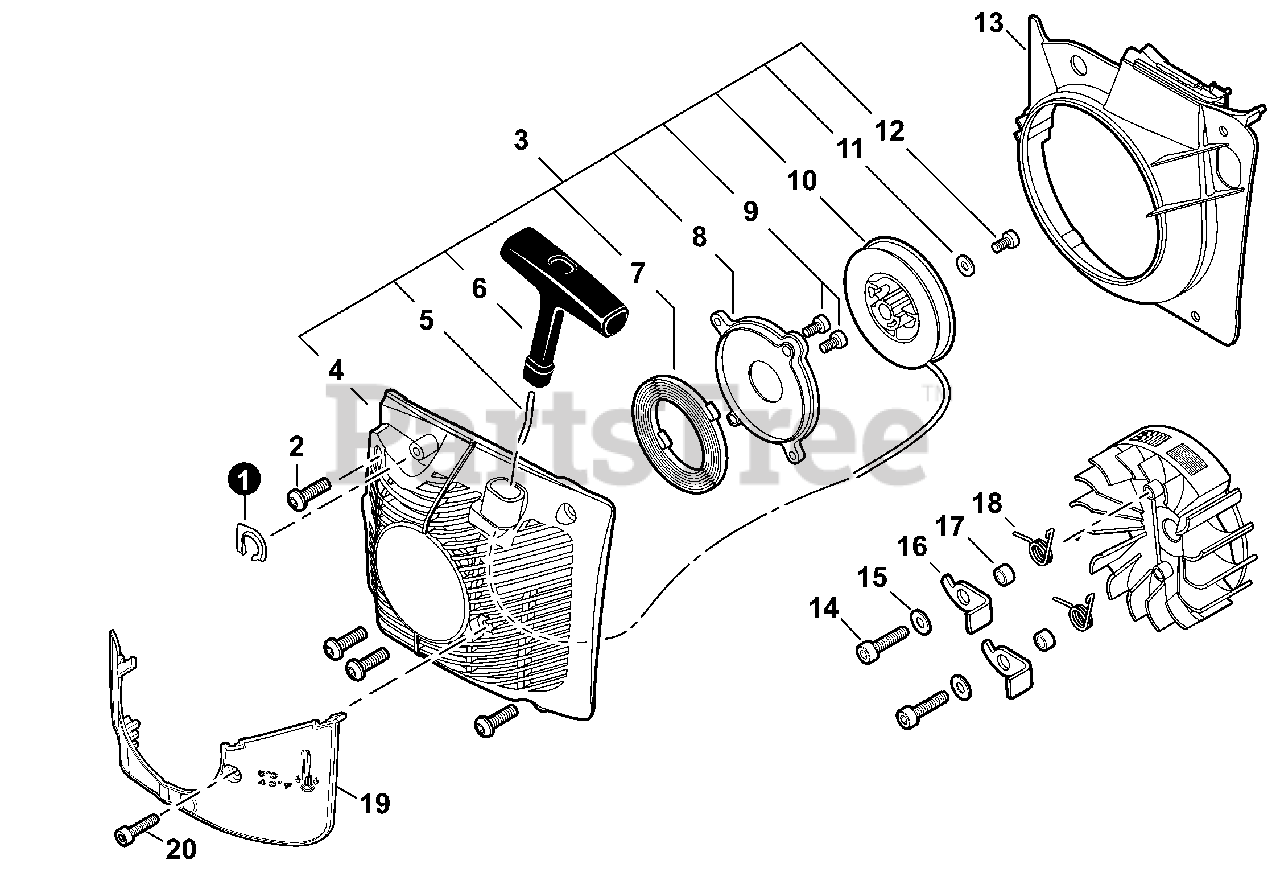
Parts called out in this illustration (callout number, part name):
1	PLATE, EYE
2	BOLT, TORX 5×20
3	STARTER ASSY, RECOIL
4	CASE, STARTER
5	ROPE, STARTER Ø4×950
6	GRIP, STARTER
7	SPRING, RECOIL
8	PLATE, STARTER
9	BOLT, TORX 4×12
10	REEL, ROPE
11	WASHER 5.2×16×1.0
12	BOLT, TORX 5×10
13	COVER, FAN
14	BOLT, TORX 5×16
15	WASHER 5.5×12×0.8
16	PAWL, STARTER
17	SPACER 5.2×8×2.1
18	SPRING, TORSION
19	SHIELD KIT - SNOW
20	BOLT, TORX 4×12
